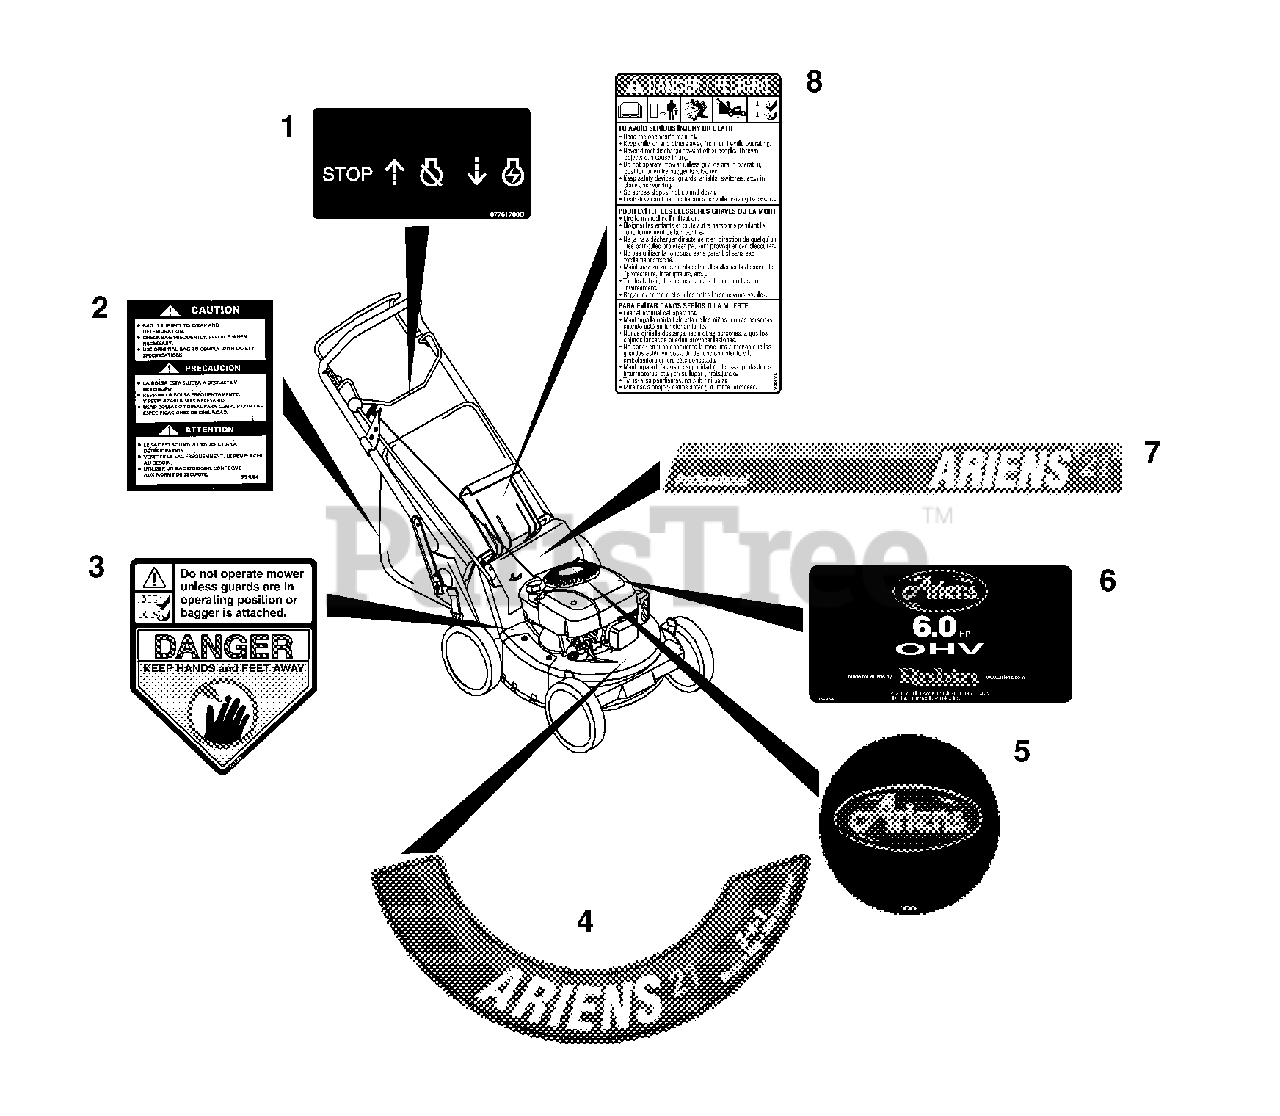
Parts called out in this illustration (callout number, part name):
1	DECAL - ENGINE CONTROL
2	LABEL - BAGGER 21"
3	DECAL, DANGER
4	DECAL, ARIENS DECK
5	DECAL, RD ARIENS ROBIN ENG RCL
6	DECAL, 6.0HP OHV ARIENS & ROB.
7	DECAL, DRIVE COVER SP PROF
8	DECAL, BILINGUAL DANGER
